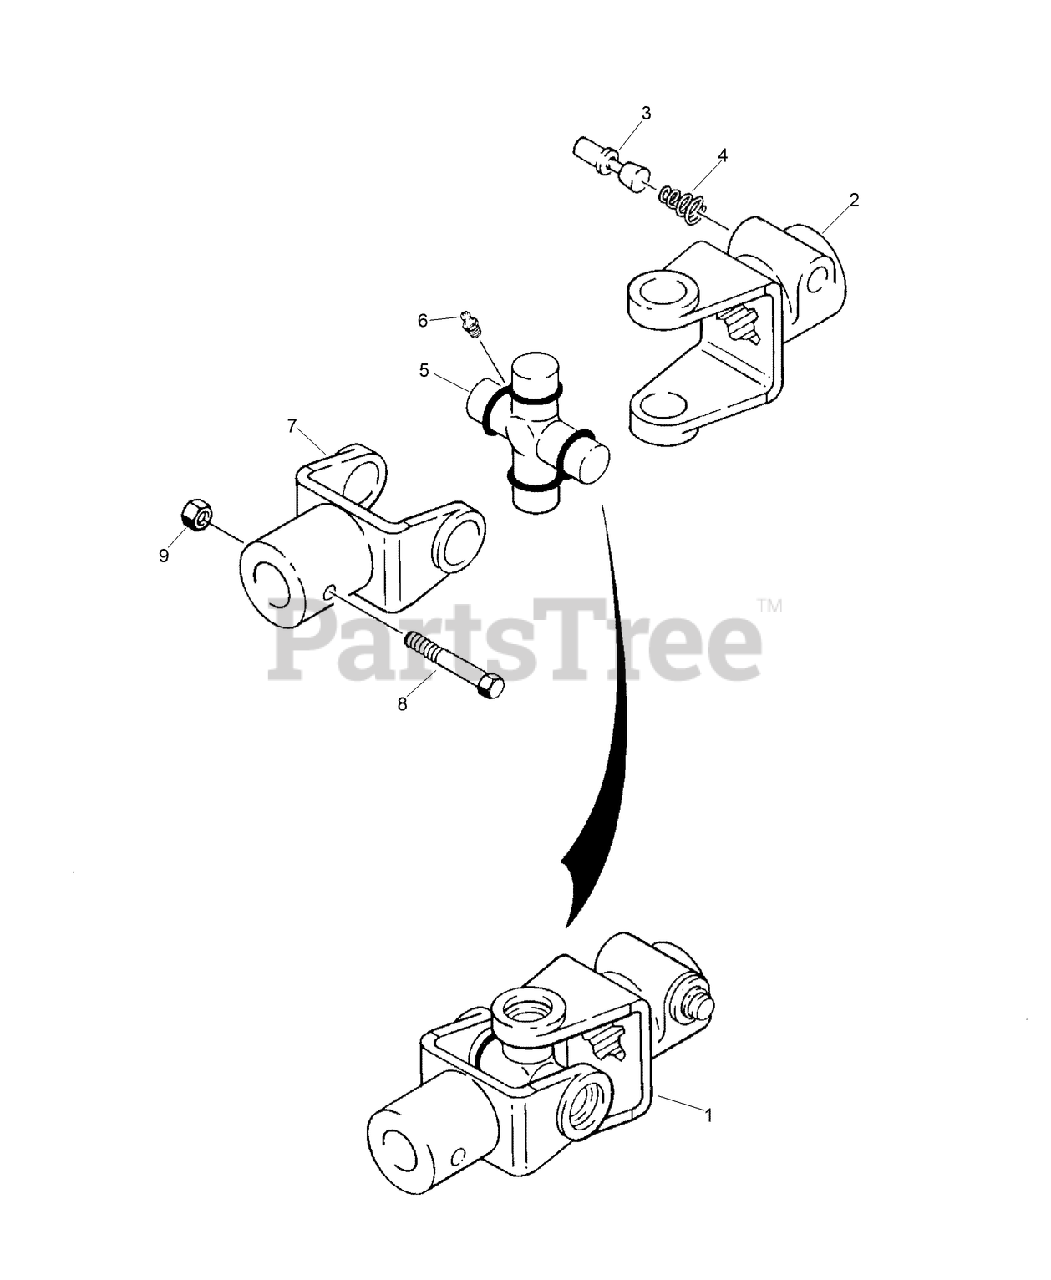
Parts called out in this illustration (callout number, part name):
1	U-JOINT ASM
2	Yoke
3	PIN - Retaining
4	SPRING - Special
5	CROSS UNION
6	FITTING-grease, straight, 1/4-28 taper x 15/16 inch
7	YOKE-boring attachments
8	SCREW-HH
9	NUT
